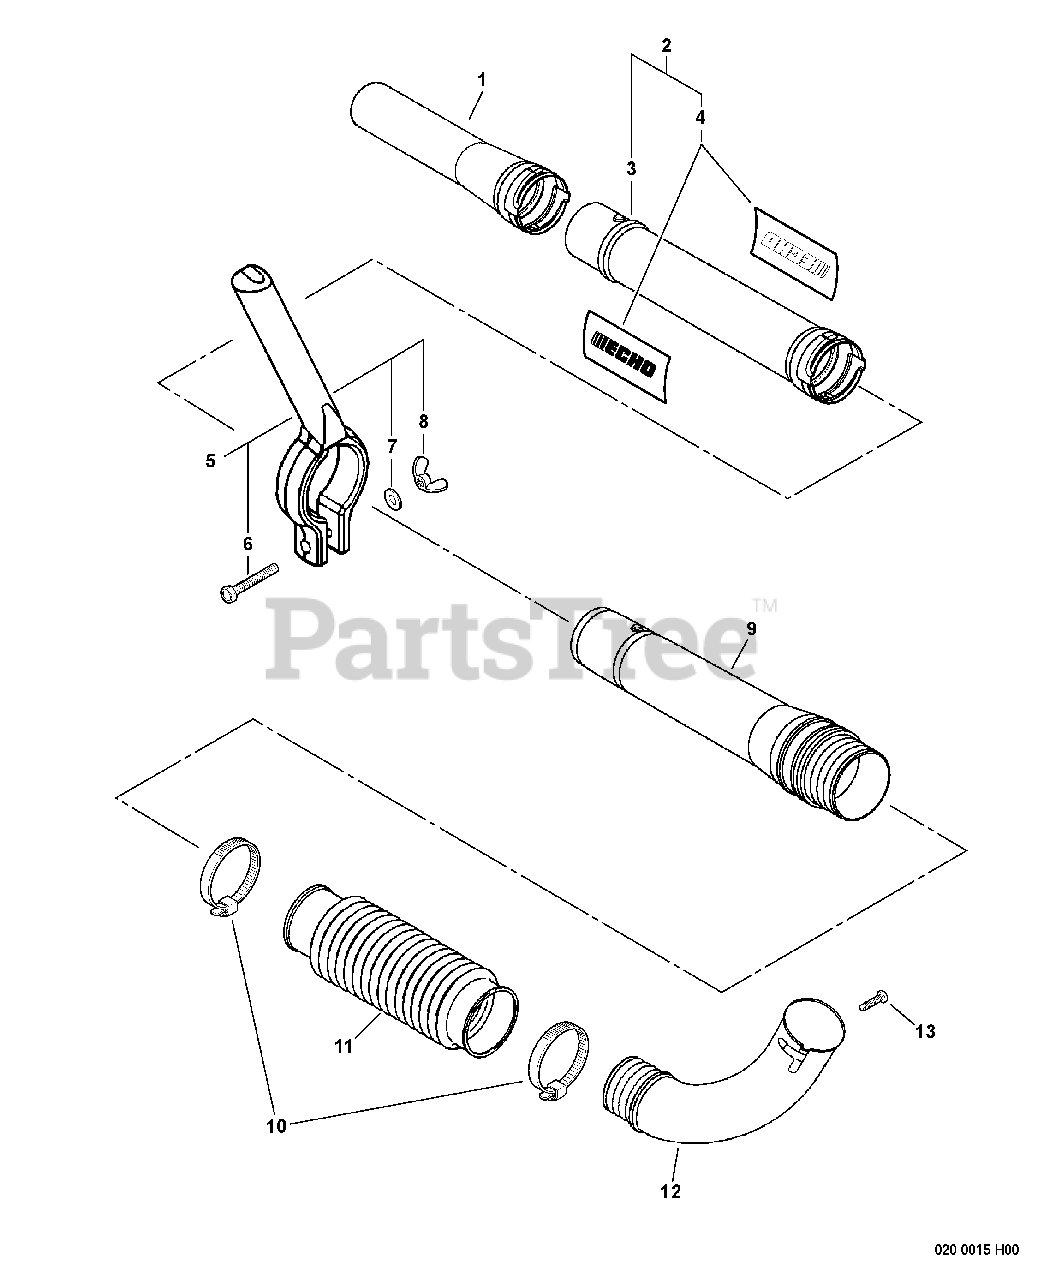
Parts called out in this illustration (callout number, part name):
1	TUBE, BLOWER
2	BLOWER TUBE KIT - STRAIGHT
3	TUBE, BLOWER - STRAIGHT
4	LABEL, ECHO BLOWER TUBE
5	HANDLE ASSY
6	BOLT 6×45
7	WASHER 6.5×11.5×0.8
8	NUT, WING 6
9	TUBE, SWIVEL
10	CLAMP 58.7 MM / 82.5 MM
11	TUBE, BLOWER - FLEXIBLE
13	SCREW, TAPPING
